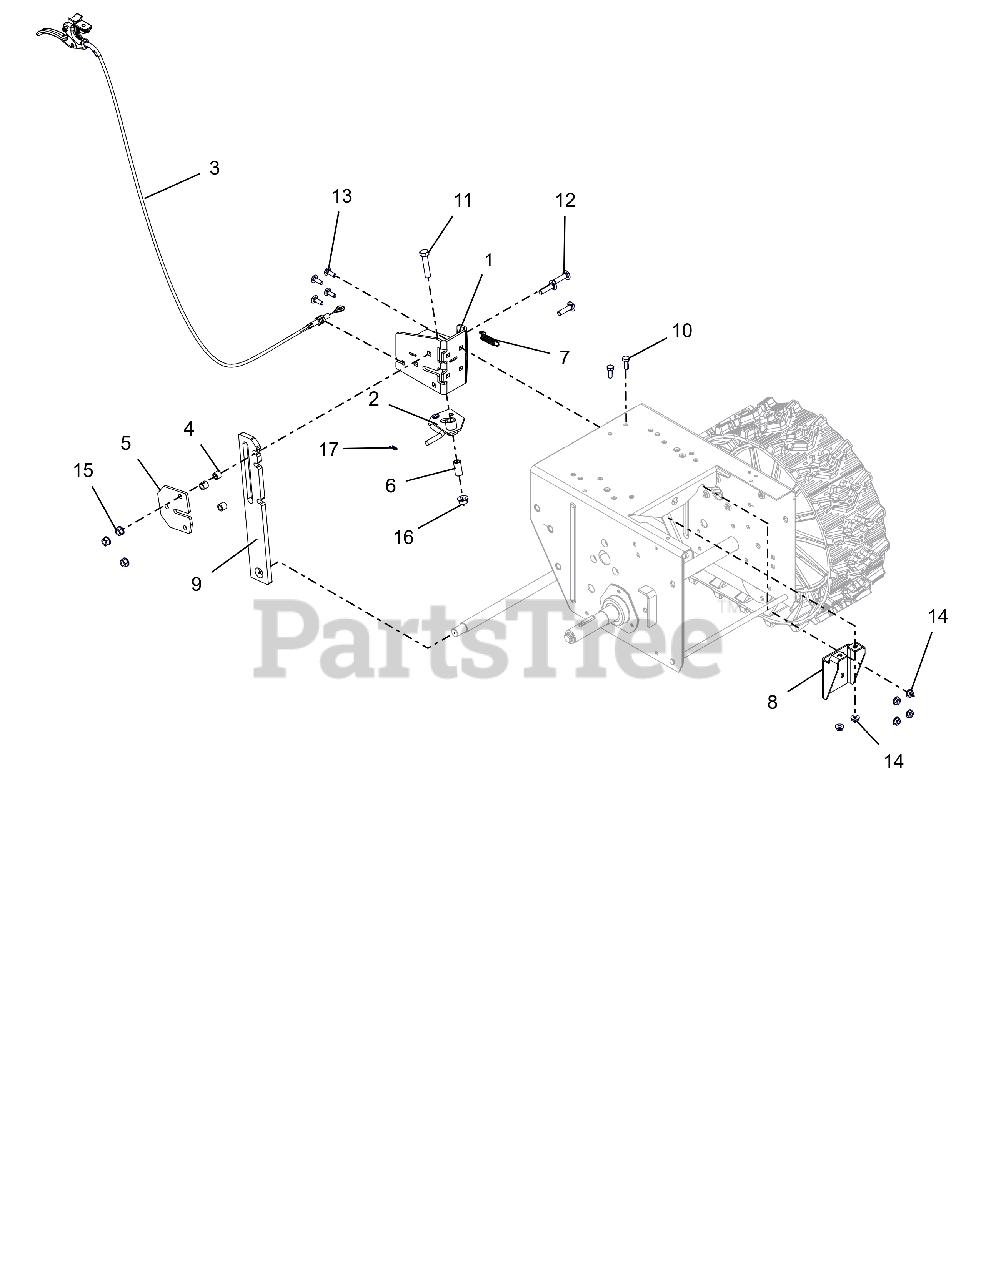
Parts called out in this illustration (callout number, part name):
1	BRACKET,HEIGHT ADJUSTER-DELUXE
2	LOCK,HEIGHT ADJUSTER TRIGGER
3	CABLE, TRACK REMOTE
4	SPACER .50 X .32 X .42
5	PLATE, HEIGHT ADJUSTER
6	BSHG-SLV .385X.500X1.045
7	SPRING-EXT .047 X .438 X 1.85
8	BRACKET, REINFORCEMENT
9	ADJUSTER, HEIGHT-BWT
10	BLT, HEX .25-20X.75 G5 ZCC
11	BLT, HEX .38-16X1.75 G5 ZCC
12	BLT, RHSSN.31-18X1.25 G5 ZCC
13	BLT, RHSN .25-20X.750 G5 ZCC
14	NUT-LK-CTR-FLG .25-20 ZC120
15	NUT-LK-TOP-FLG .312-18 GF ZCC
16	NUT-LK-CTR-FLG .375-16 GF ZCC
17	PIN, HAIR #178 .06X.77 ZCC
